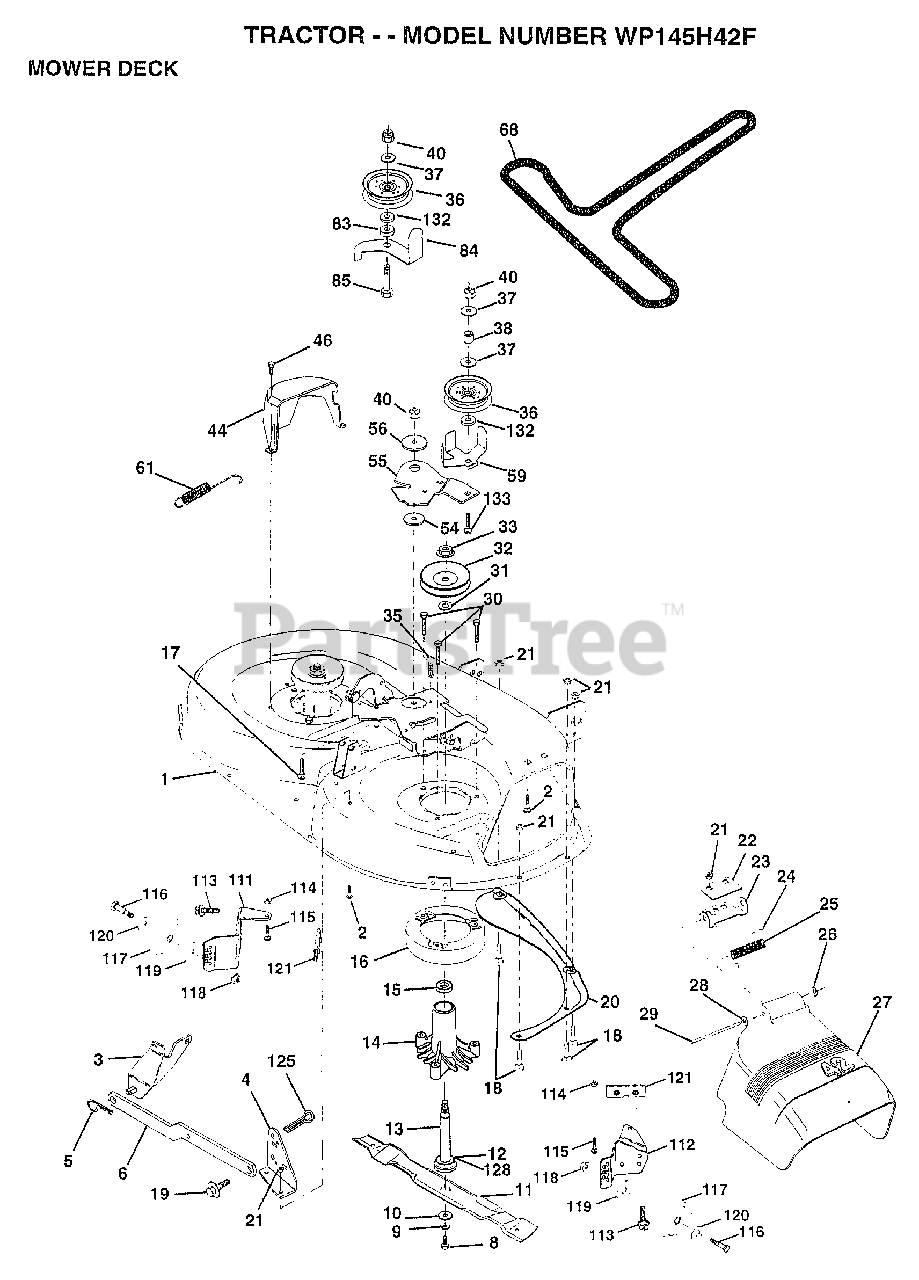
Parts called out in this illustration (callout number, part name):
1	"HOUSING ASSY.42"""
2	BOLT
3	BRKT ASM SWAY BAR
4	BRKT DECK SW BAR
8	BLADE BOLT
10	WASHER.HARD.BLADE
11	"BLADE.42"" HIPERF"
12	BEARING.BALL
14	HSG ASM MANDREL
15	BEARING
16	STRIPPER RND MWR
17	BOLT CARRIAGE
18	BOLT
19	BOLT SHD 5/16-18
20	BAFFLE VORTEX 42
22	STIFFENER BRKT
23	DEFLECTOR BRKT
25	SPRING TORSION
27	DEFLECTOR.SHIELD
28	WASHER
29	HINGE ROD
30	"SCREW-THD ROLL,WA"
31	WASHER
32	PULLEY.MANDREL.42
35	XMAS TREE FASTNER
36	FLAT IDLER PULLEY
37	WASHER
44	GUARD MAND LH BLK
46	SCREW.1/4-20X5/8
54	HARDENED WASHER
56	SPACER RETAINER
59	GUARD IDLER TUV
61	SPRING.EXTENSION
68	BELT.V.T-PATH
83	WASHER
84	"KEEPER-BELT,FIXED"
85	BOLT
111	BRACKET.GWHL.LH.
112	BRACKET.GWHL.RH.
113	SCREW
116	BOLT M
117	WHEEL.GAGE.BLK.PL
118	LOCKNUT
119	WASHER
120	WASHER
121	BRACKET.EXTRD.GWL
128	WASHER.FELT.
132	WASHER GT
133	BOLT
